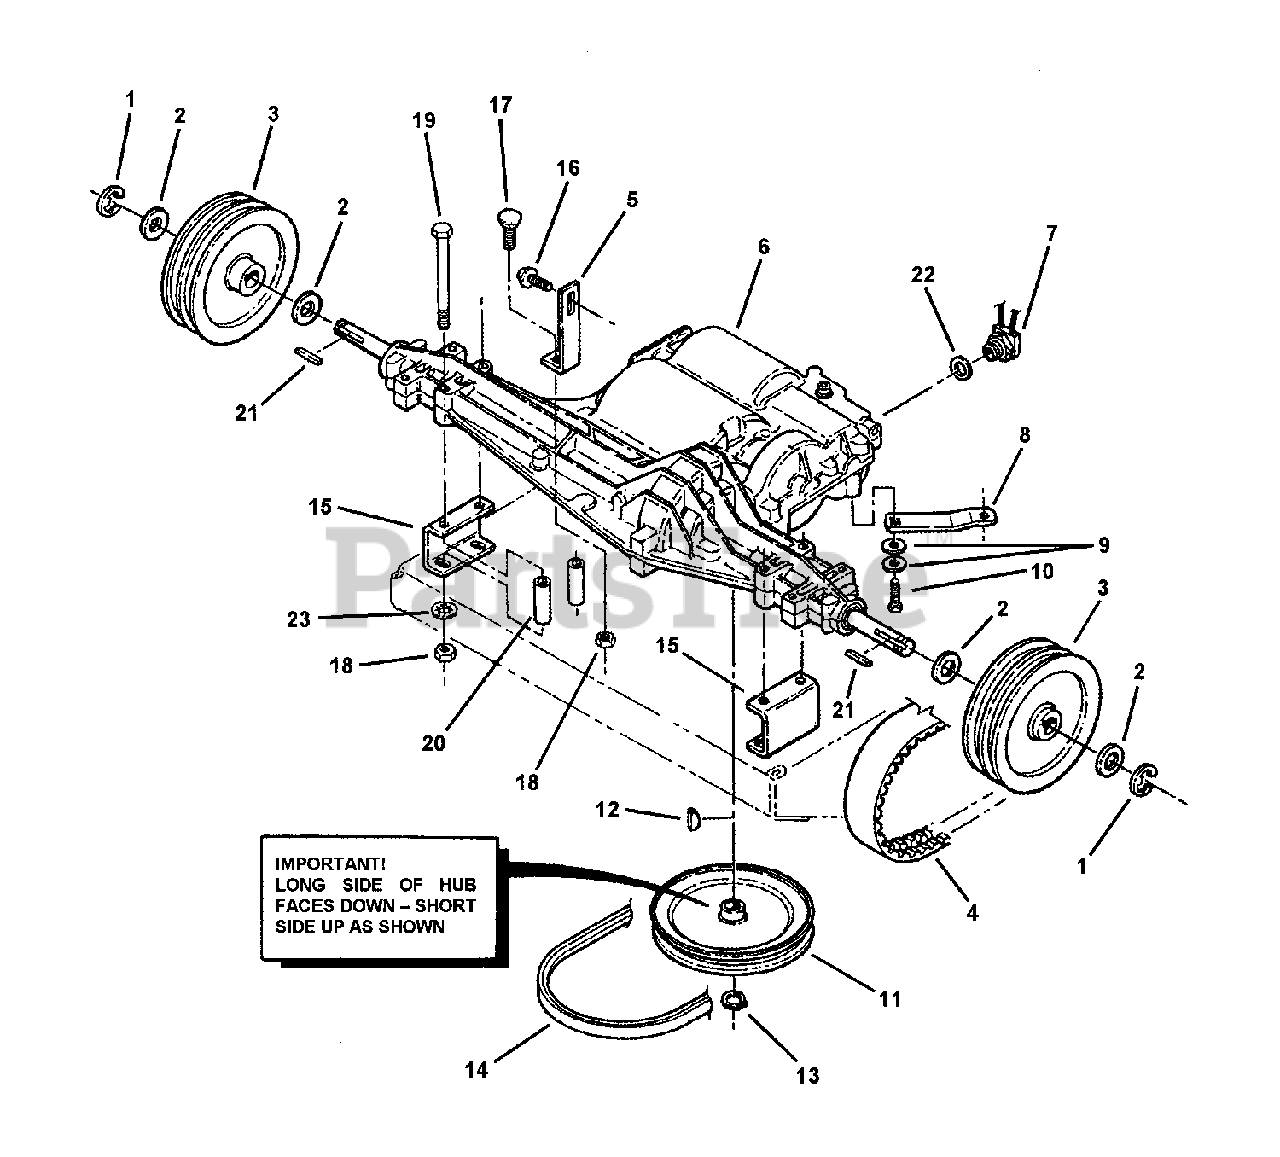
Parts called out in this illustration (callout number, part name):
1	RING, 3/4" External Retaining
2	WASHER, 3/4 x 1-1/8" x .06 Flat
3	PULLEY, Trans Output, 5.5" Dia., 2RA
4	BELT, Traction, 2RAX Sect. Eff. Length 53.4
5	TORQUE BRACKET
6	TRANSMISSION, Peerless, 5-Speed
7	SWITCH, Transmission (NO)
8	SHIFT ARM, Express
9	WASHER 1/4" Bellville
10	BOLT, 1/4-28 x 5/8" Hex w/Nyloc Patch, GR 8
11	PULLEY, Transmission Input
12	KEY, #9 Woodruff
13	RING, External Retaining
14	V-BELT, HA, Effective Length 41.650
15	SUPPORT, Transmission
16	SCREW, 5/16-18 x 5/8" Hex Washer Self-Tap
17	BOLT, 5/16-18 x 1" Square Neck Carriage, GR 5
18	NUT, 5/16-18 HEX NYLON LOCK
19	SCREW, 5/16-18 x 4-1/2" Hex Head Cap, GR 5
20	SPACER, Transmission
21	KEY, 3/16" Square x 1"
22	WASHER, Fiber
23	RETAINER, 5/16" Bolt
